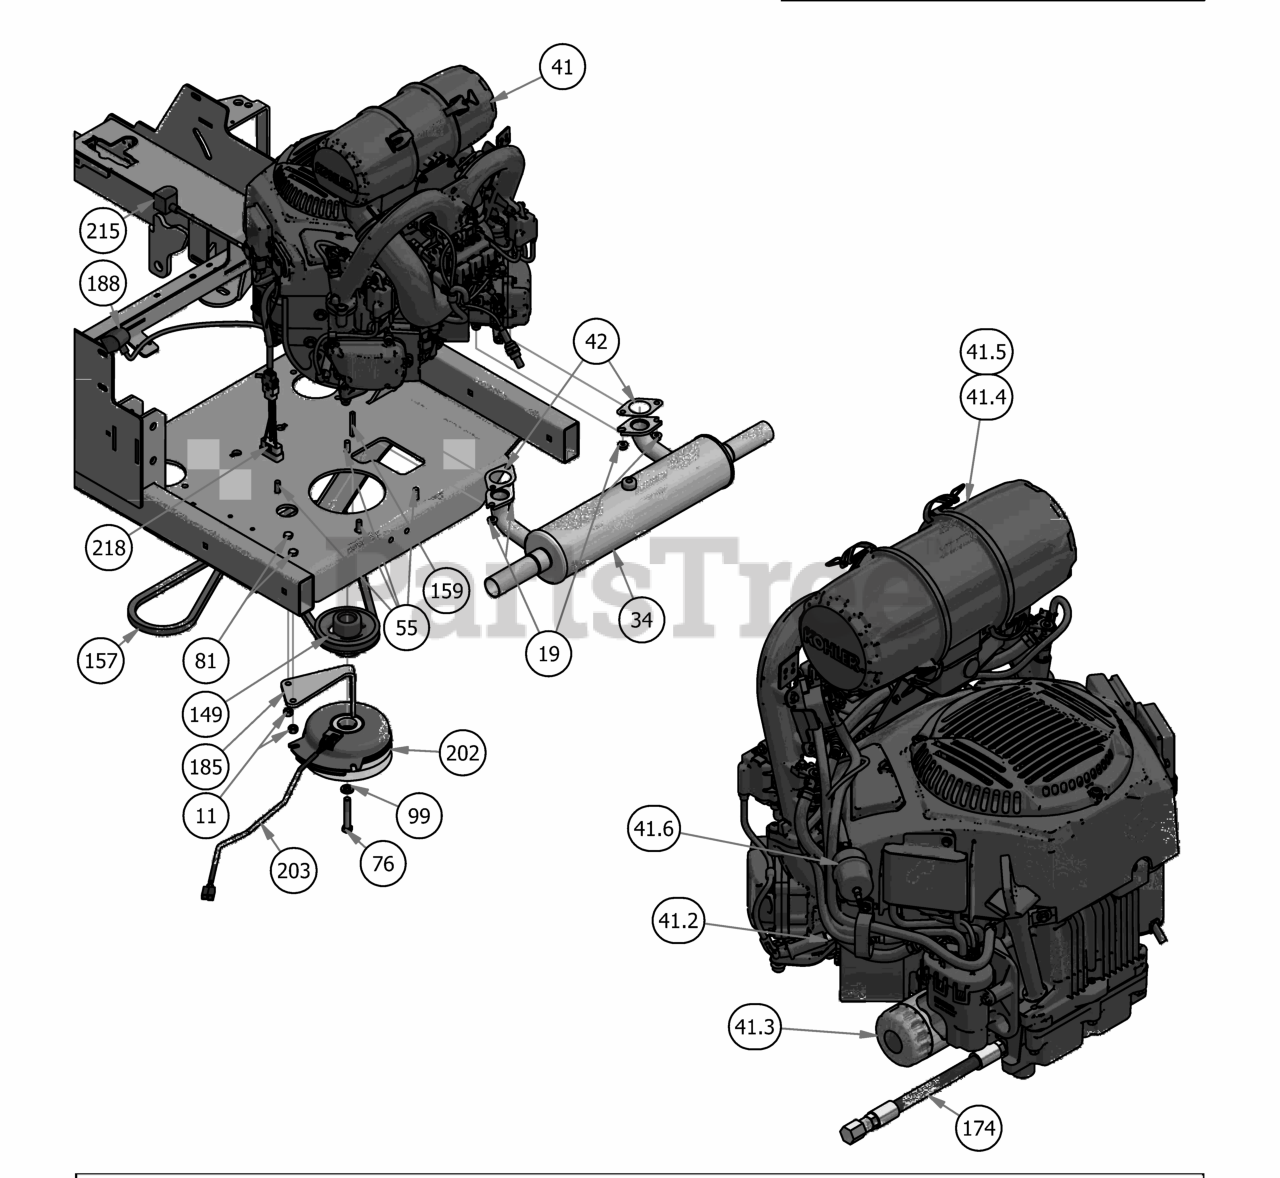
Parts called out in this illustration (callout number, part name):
11	3/8" Hex Nut
19	M8 Flange Nut for Kohler Exhaust
34	Muffler for 33Hp 824cc Kohler Engine
41	824cc EFI Kohler
41.2	Spark Plug
41.3	Oil Filter
41.4	Canister Air Filter- Inner
41.5	Canister Air Filter- Outer
41.6	25/26 HP Kohler Fuel Filter
42	Exhaust Gasket for 824EFI Kohler
55	3/8 x 1 1/8 bolt
76	7/16" x 2 1/2" Hex Bolt
81	3/8" x 1" Hex Bolt
99	7/16" Lock Washer
149	4 3/4 Motor Pulley
157	2019 Rogue Pump Belt 68"
159	1/4 x 2 Square key Stock
174	Oil drain Hose
185	PTO Engager Holder
188	24" Red Battery Cable
202	Clutch Assembly
203	Clutch Pigtail
204	2019 Veritical Suspension Frame
215	Starter Cable
218	2019 Harness Adaptor - Vanguard 37 EFI Vert/Horiz
